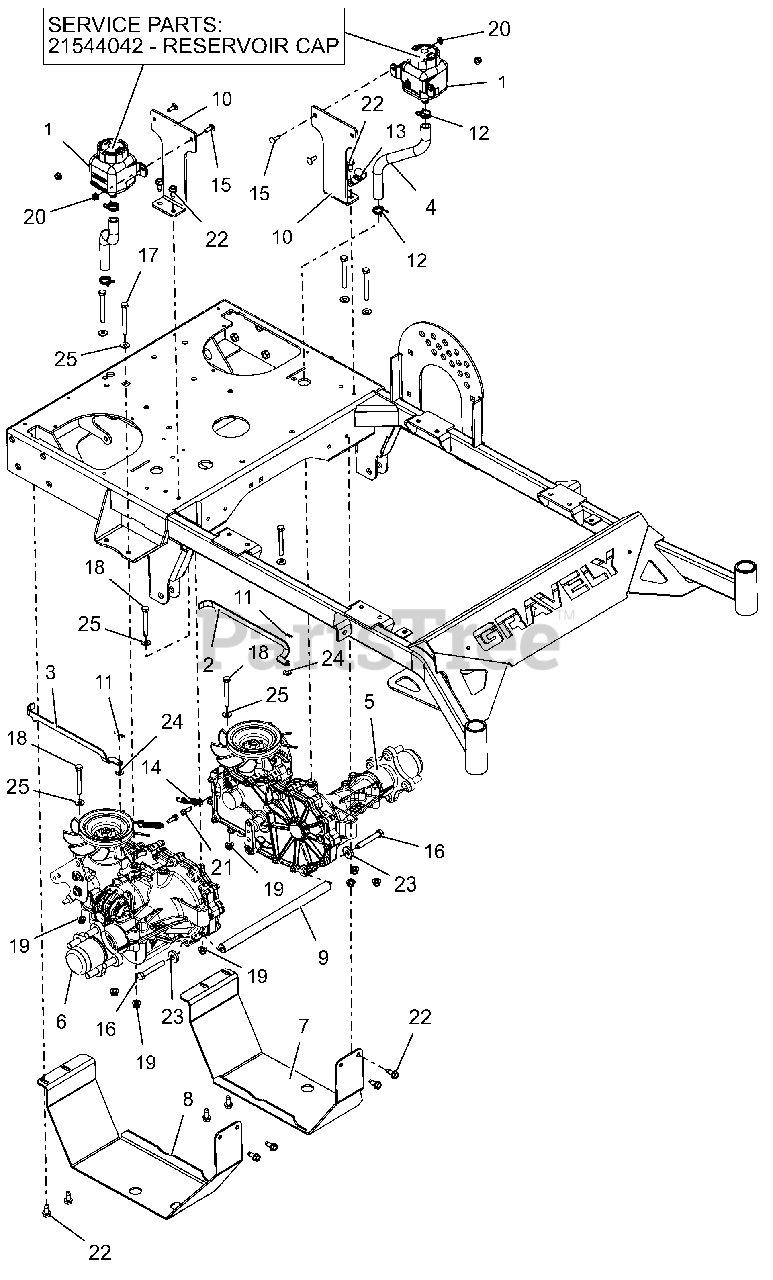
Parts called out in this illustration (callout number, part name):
1	TANK, EXPANSION
1	CAP, HYDRO RESERVOIR REPLAC.
2	BRKT, LH DUMP VALVE (BLACK)
3	BRKT, RH DUMP VALVE (BLACK)
4	HOSE, PRO WALK OVERFLOW
5	TRANSAXLE, ZT2800 - LH
6	TRANSAXLE, ZT2800 - RH
7	PLATE, LH SKID (BLACK)
8	PLATE, RH SKID (BLACK)
9	SHAFT, CROSS BRACE
10	BRKT, EXPANSION TANK MTG (RED)
11	PIN-HAIR, ENDRIES #25 YWZC
12	3/4 WIRE HOSE CLMP ZC
14	SPRING, EXTENSION
15	@BLT-RDHDSQNK .25-20X.75 G5YZ
16	@BLT-HEX .38-16X2.50 GR5 YWZC
17	@BLT-HEX .31-18X2.75 GR5 YWZC
18	@BLT-HEX .31-18X2.50 GR5 YWZC
19	@NUT-LK-NYL-FLG .31-18 YWZC
20	@NUT-LK-NYL-FLG .25-20 YWZC
21	SCR-TAP-PM .25-20X.75 TR YWZ
22	@SCR-TAP .31-18X.75 HWH TR YWZ
23	WSHR-FL-STL .406X1.00X.188 YWZ
24	@WSHR-FL-STL.281X.62X.065 YWZC
25	@WSHR-FL-STL.312X.734X.065 YWZ
